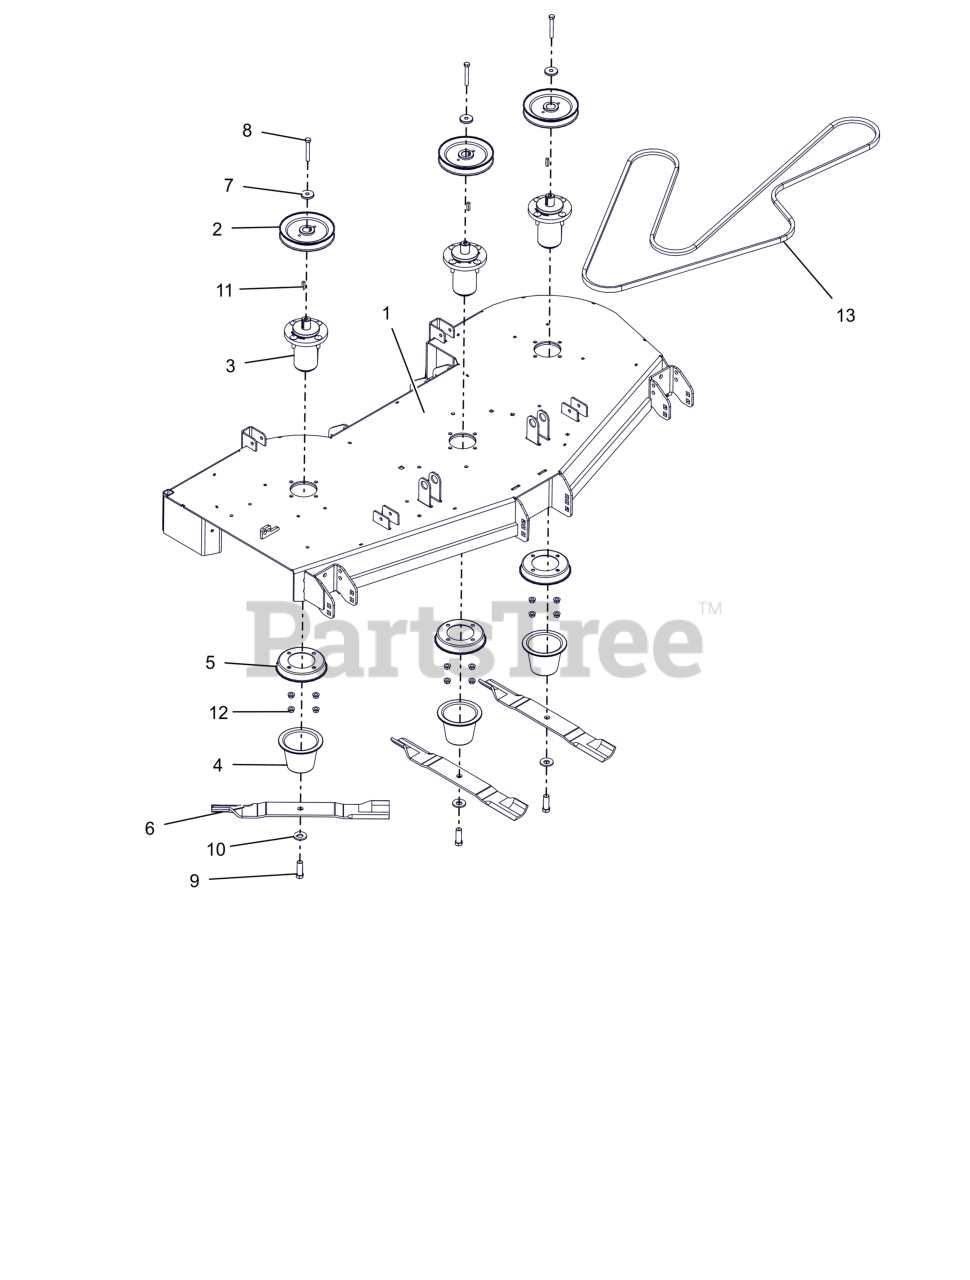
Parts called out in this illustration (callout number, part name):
1	WLDMT, 60" PROSTANCE DECK (RED)
2	PULLY, 1.00 ID X 6.34
3	ASM, MAINT FREE ALUM SPINDLE
4	GUARD, SPINDLE LOWER
5	GUARD, SPINDLE TOP
6	BLADE, MOWER (20.50")
7	RETAINER, SHEAVE
8	BLT, HEX .38-16X2.75 G8 ZCC
9	BLT, HEX .62-18X1.75 G8 ZCC
10	WSHR-BLVL .669X1.535X.138
11	KEY, SQ .25X.25X1.00 RC 40-50
12	NUT-LK-CTR-FLG .375-16 GF ZCC
13	V-BELT, B RAW EDGE EPDM
